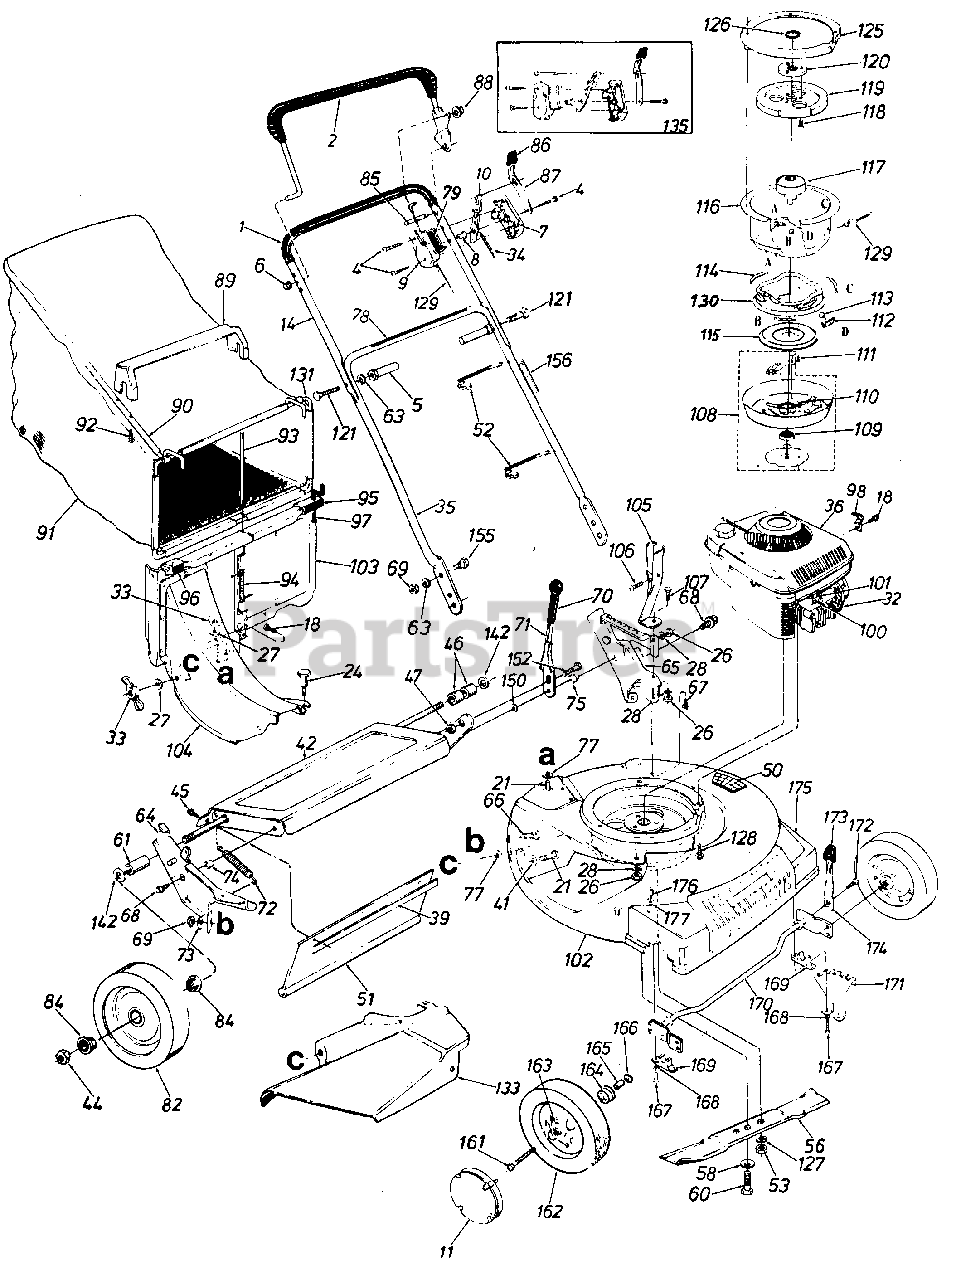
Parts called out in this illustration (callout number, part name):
2	Control Handle Ass'y. L.H.
4	Truss Mach. Scr. #12 x 1.50" Lg.
5	Catcher Support Pin
6	Push Cap
7	Control Panel Half
8	Control Disc Pin
9	Clutch Panel Half
10	Throttle Control Lever
11	Hub Cap
14	Upper Handle Chrome
18	Hex B-Tap Scr #10 x .38"
21	Carriage Bolt 1/4-20 x .62"
24	Shoulder Bolt .312 Dia. x .18 Lg. Special
26	Hex Nut 1/4-20 Thd.
27	Bell-Wash. 1/4" I.D.
28	L-Wash. 1/4" I.D.
32	Spark Plug Insulator
33	Wing Nut
34	Throttle Control Wire 58"
35	Lower Handle Chrome
36	Engine
39	Retaining Strip
41	Fl-Wash. .344" I.D. x .62"
42	Rear Axle Ass'y.
44	Hex L-Nut 1/2-20 Thd.
45	Hex AB-Tap Scr. 1/4 x .62"
46	Spacer.526" I.D.
47	Hex Patch L-Nut 3/8-24 Thd.
50	Rubber Foot Pad
51	Rear Flap
52	Cable Tie
53	Hex Nut 3/8-24 Thd. (Grade 8)
56	21" Blade
58	Bell-Wash. .460" I.D. x .880"
60	Hex Bolt 7/16-20 x 2.0"
61	Sleeve .526" I.D.
63	L-Wash. 5/16" I.D.
64	R.H. Handle Wheel Brkt. Ass'y.
65	L.H. Handle Wheel Brkt. Ass'y.
66	Carriage Bolt 5/16-18 x .62"
67	Hex Wash. Hd. B-Tap Scr. 5/16-18
68	Hex Wash. Hd. TT-Tap Scr. 3/8-16
69	Hex Nut 5/16-18 Thd.
71	Height Adj. Lever
72	Extension Spring 3.80" Lg.
73	Bell-Wash. 5/16" I.D.
74	Spacer.385" I.D.
75	Shld. Spacer .5" Dia.
77	Bolt Retainer 1/4 x .50" O.D.
78	Instruction Label
79	Control Label
82	Wheel Ass'y. Comp. Rear
84	Flange Bali Bearing 1/2" I.D.
85	Lock Pin .314" Dia. x 1.75"
86	Spring Lever Knob
87	Lockout Spring
88	Push Cap
89	Bag Handle
92	Truss Mach. B-Tap Scr. #12 x 1.5" Lg.
93	Chute Rod .188" Dia.
94	Torsion Spring
95	Door Clip
96	Panel Clip
97	Hex AB-Tap Scr. 1/4 x .75" Lg.
98	Casing Clamp
100	Hex B-Tap Scr. #10 x .62"
101	Casing Clamp
104	Top Discharge Chute Ass'y.
105	Grass Catcher Bracket
106	Truss Mach. Scr. 1/4-20 x .50" Lg.
107	Hex Bolt 1/4-20 x .50" Lg.
108	Clutch Blade Housing Ass'y.
109	Ball Bearing
110	Compression Spring
111	Hex Wash. TT-Tap Scr. 1/4-20 x.75" Lg.
112	Ball Block
113	Steel Ball
114	Ext. Spring 1.75" Lg.
115	Clutching Cone
116	Clutch Housing
117	Fixed Pulley Adaptor
118	Flat Hd. B-Scr. 1/4-20 x .62" Lg.
119	Flywheel
120	Flywheel Adaptor
121	Curved Carr. Bolt 5/16-18 x 1.75" Lg.
125	Engine Mntg. Cover plate Ass'y.
126	Serrated Wash. 1.0" I.D.
127	L-Wash. 3/8" I.D.
128	Hex Wash. Hd. Tap Scr. 3/8-16 x 1.51" Lg.
129	Control Cable-46"
130	Brake Cup Cone
131	Front Catcher Frame
133	Side Chute Deflector Ass'y.
135	Kit Control Housing Comp.
142	Fl-Wash. .510" I.D. x .75"
150	Fl-Wash. 3/8" I.D. x 1.0"
152	Hex Bolt 3/8-24 x .75" Lg.
155	Truss Mach. Scr. 5/16-18 x .75" Lg.
156	Plastic Tubing
161	Hex Bolt 3/8-16 x 1.75" Lg.
162	Wheel Ass'y. Comp. 8 x 2
163	Flange Ball Brg. 3/8" I.D.
164	Flange Ball Brg. .501" I.D.
165	Spacer
166	Bell-Wash. .400" I.D. x .88
167	Hex Wash. Hd. B-Tap Scr. 1/4 -20
168	L-Wash. 1/4" I.D.
169	Block Bushing
170	Axle Ass'y.
171	Height Adj. Bracket
172	Hex Wash. Hd. B-Tap Scr. 1/4-20 x .75" Lg.
173	Knob
174	Spring Lever
175	Plastic Front End
176	Truss B-Tap Scr. 5/16 x .75" Lg.
177	Bell-Wash. 5/16" I.D. x 5/8
